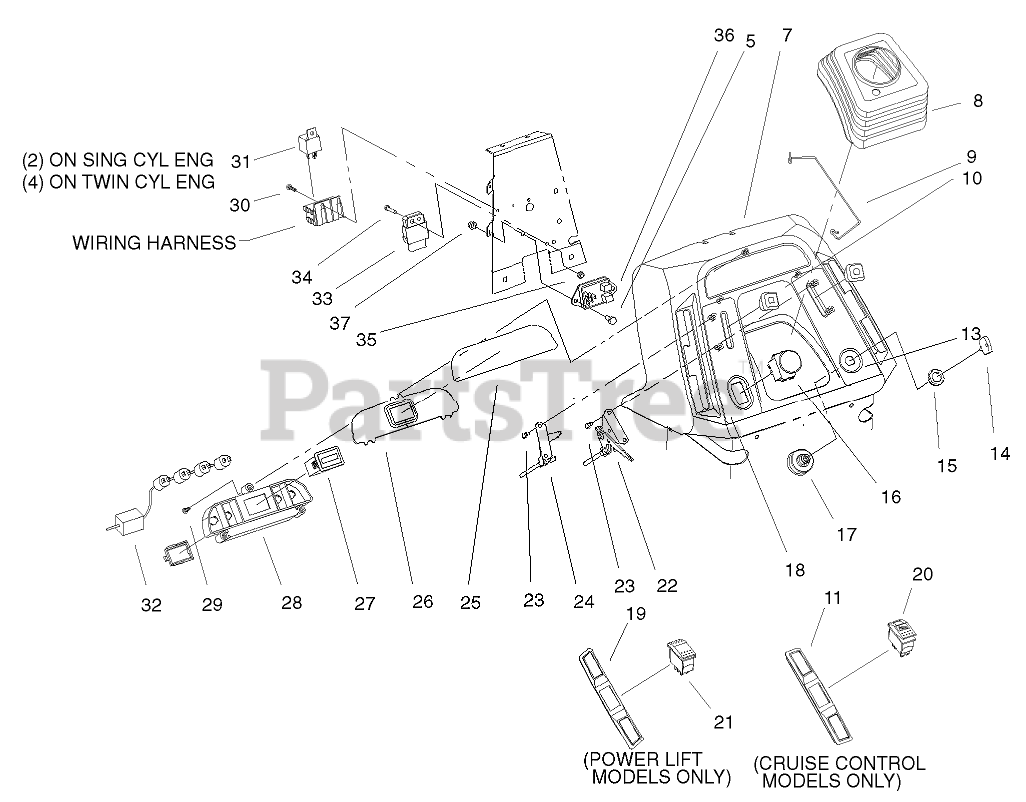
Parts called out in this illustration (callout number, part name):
5	SCREW-HH
8	BOOT-STEERING
9	CLIP-BOOT
11	Cover-RH Slot (only on: 72116)
11	Cover-RH Slot (only on: 72108)
13	Decal-Throttle/Ign (only on: 72108)
13	Decal-Dash Throt/Ign (only on: 72116)
14	KEY-IGNITION
16	SWITCH-PTO
17	SWITCH-IGNITION
18	Decal-Dash PTO/Choke (only on: 72116)
18	Decal-PTO/Choke (only on: 72108)
19	Cover-Lift (only on: 72116)
19	Cover-Lift (only on: 72108)
20	SWITCH-CRUISE
21	SWITCH
22	CONTROL-THROTTLE (TWIN)
24	CONTROL-CHOKE (TWIN)
25	DECAL - DASH LENS
26	LENS-DASH
27	HOURMETER
28	HOUSING-LIGHT
29	SCREW
30	SCREW-PPHTF
31	RELAY
32	HARNESS-6 LAMP
33	MODULE-LOW VOLTAGE
35	NUT-LOCK, NI
36	MODULE-CLUTCH
37	NUT-LOCK, NI
